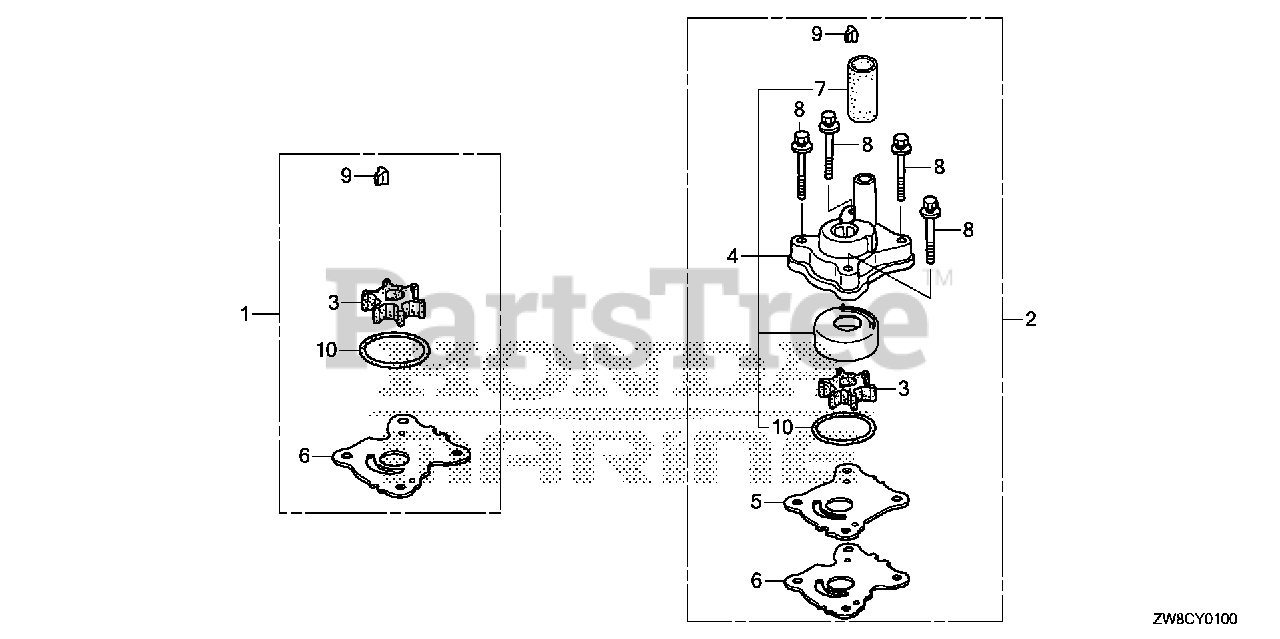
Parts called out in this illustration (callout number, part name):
1	PUMP KIT, IMPELLER
2	PUMP KIT, IMPELLER
3	IMPELLER, PUMP (S,L)
4	HOUSING ASSY., IMPELLER
5	COVER, IMPELLER
6	GASKET, IMPELLER
7	RING, WATER TUBE SEAL
8	BOLT-WASHER (6X50)
9	KEY, WOODRUFF
10	O-RING (42.2X2.4)
